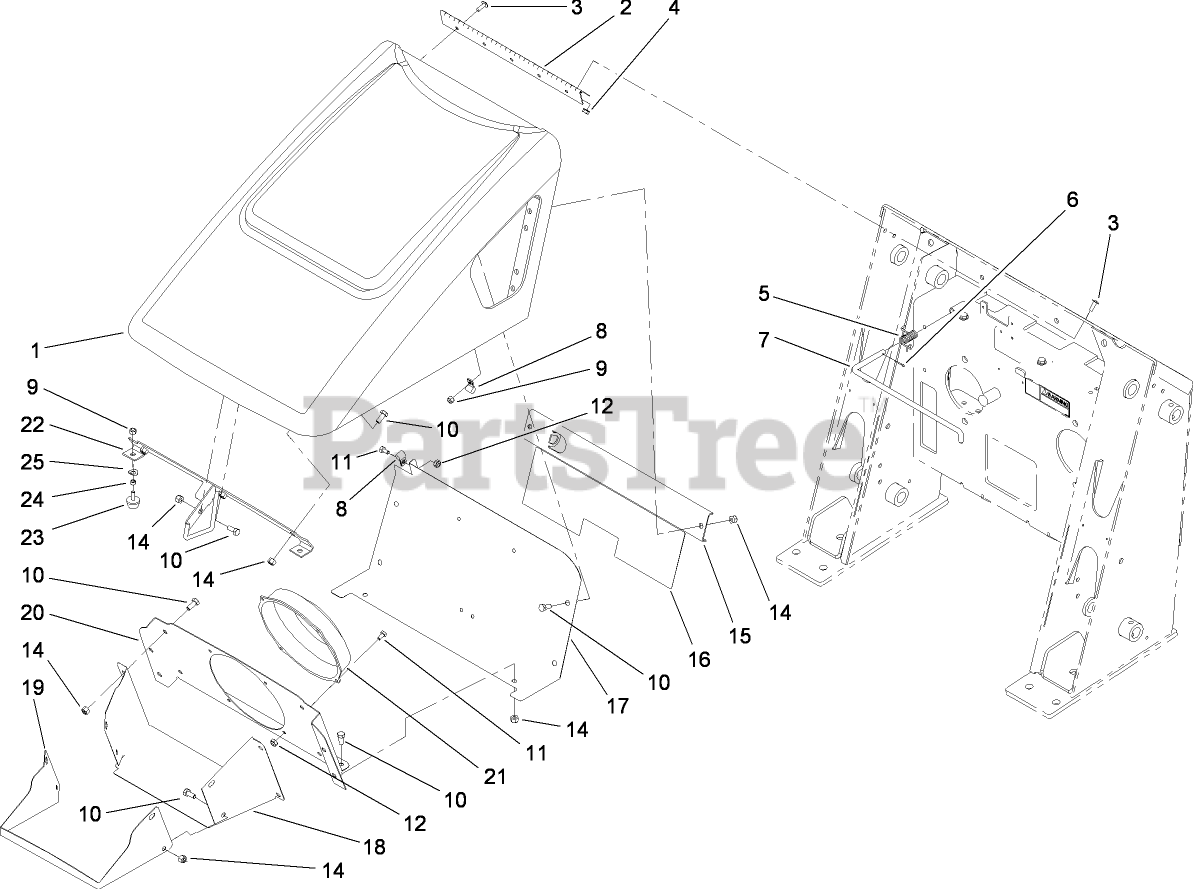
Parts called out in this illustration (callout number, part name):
1	Engine Hood ASM
2	HINGE-HOOD
3	SCREW-HEAD, TRUSS
4	NUT-HF
5	Spring-Torsion
6	PIN-COTTER
7	Rod-Support, Hood
8	CLAMP
9	NUT-LOCK, NI
10	SCREW-HH
11	SCREW-HH
12	NUT-LOCK, NI
14	NUT-LOCK, NI
15	BRACKET-SUPPORT, HOOD
16	DECAL-SERVICE
17	BRACKET-FAN, BACK
18	SHROUD-FAN
19	SHROUD-FAN, FRONT
20	BRACKET-FAN, FRONT
22	ROD LATCH ASM
23	BUMPER
24	SPACER
25	WASHER-SPRING
